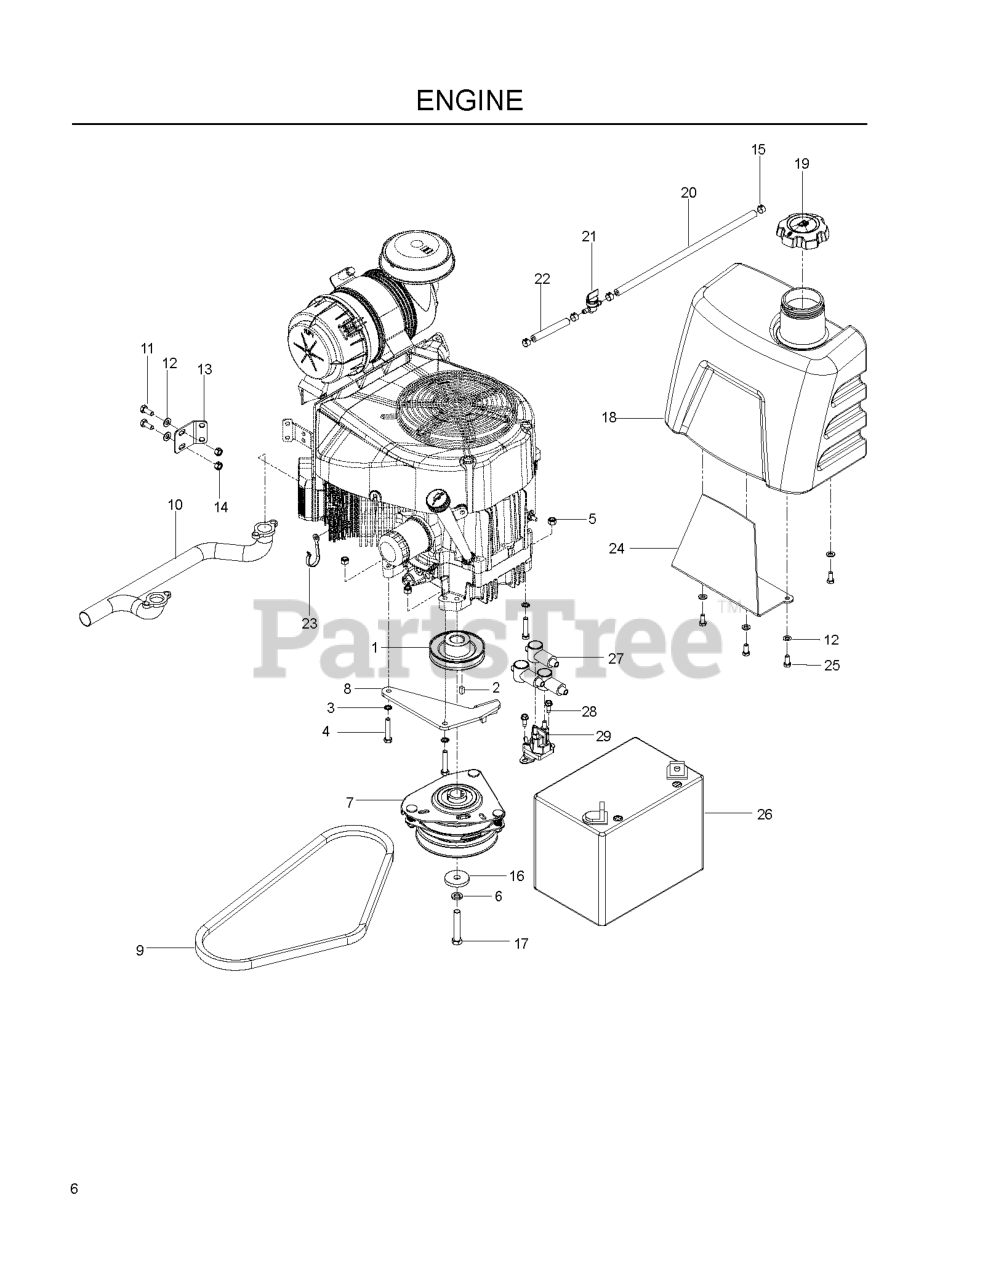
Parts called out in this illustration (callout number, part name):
1	SWITCH, BRAKE 3P
2	BUSHING, SLEEVE
3	BRAKE LEVER WLDMT
4	PLASTIC BUSHING
5	PIVOT SHAFT
6	BRAKE SHAFT
7	BRAKE LINKAGE
8	NUT 3/8-16 NYLOC
9	HAIRPIN #2
10	BOLT 5/16C X 3/4" CARRIAGE
11	WASHER 3/8 FLAT
12	NUT 3/8C WHIZ
13	HCS 3/8C X 2 1/4
14	WASHER 5/16 FLAT
15	NUT 5/16 NYLOC
16	SCREW #10 X 1/2 SELF TAPPING
17	GRIP, PARK BRAKE
